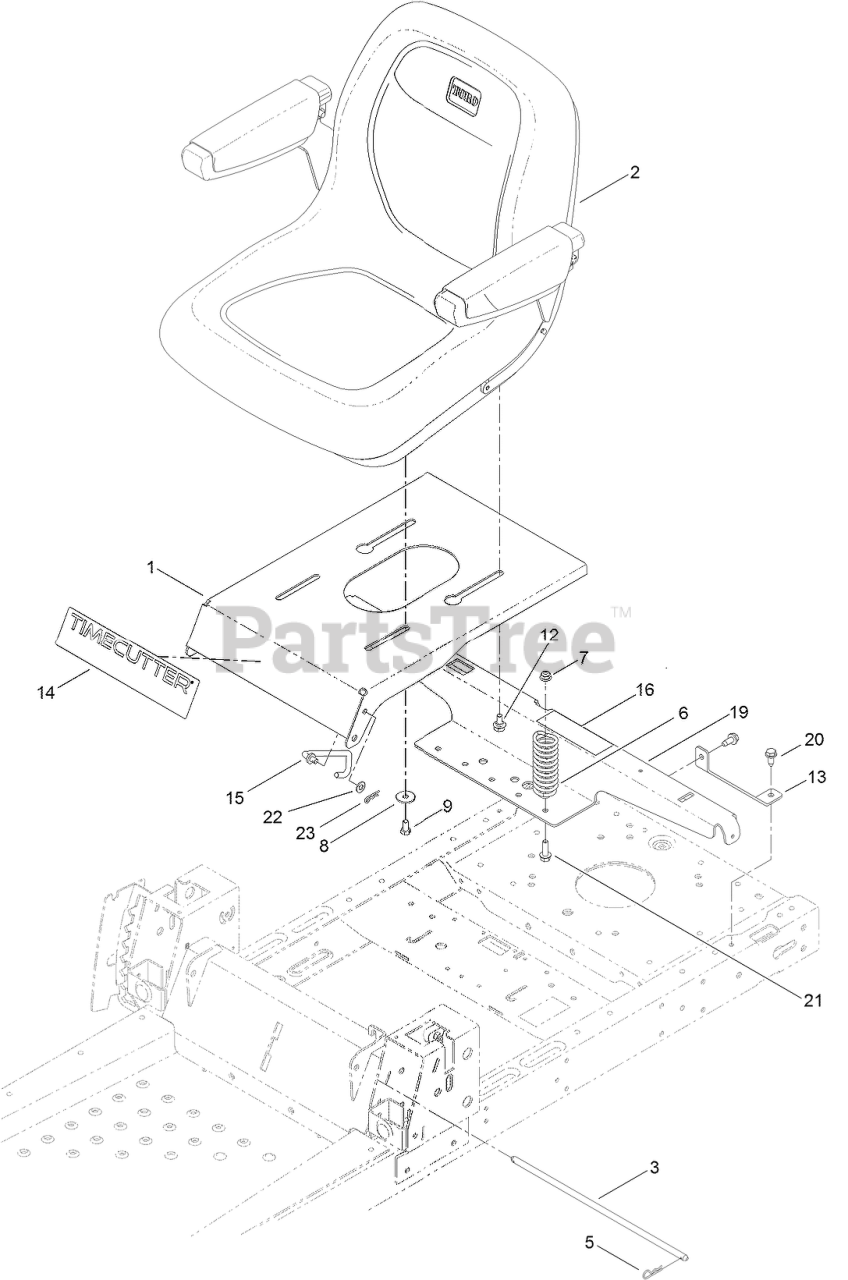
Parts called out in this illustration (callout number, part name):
1	PAN-SEAT
2	SEAT-18 Inch
3	ROD-PIVOT, NARROW
5	PIN-COTTER
6	SPRING-COMPRESSION
7	NUT-HF, NI
8	WASHER-PIVOT
9	SCREW-HH
12	BOLT-SHOULDER
13	SUPPORT-TANK, REAR
14	DECAL-TIMECUTTER
15	STOP-SEAT
16	DECAL-SERVICE, CE
19	SUPPORT-POD
20	SCREW-HWHTF
21	SCREW-HHF
22	WASHER-PLAIN
23	PIN-COTTER
